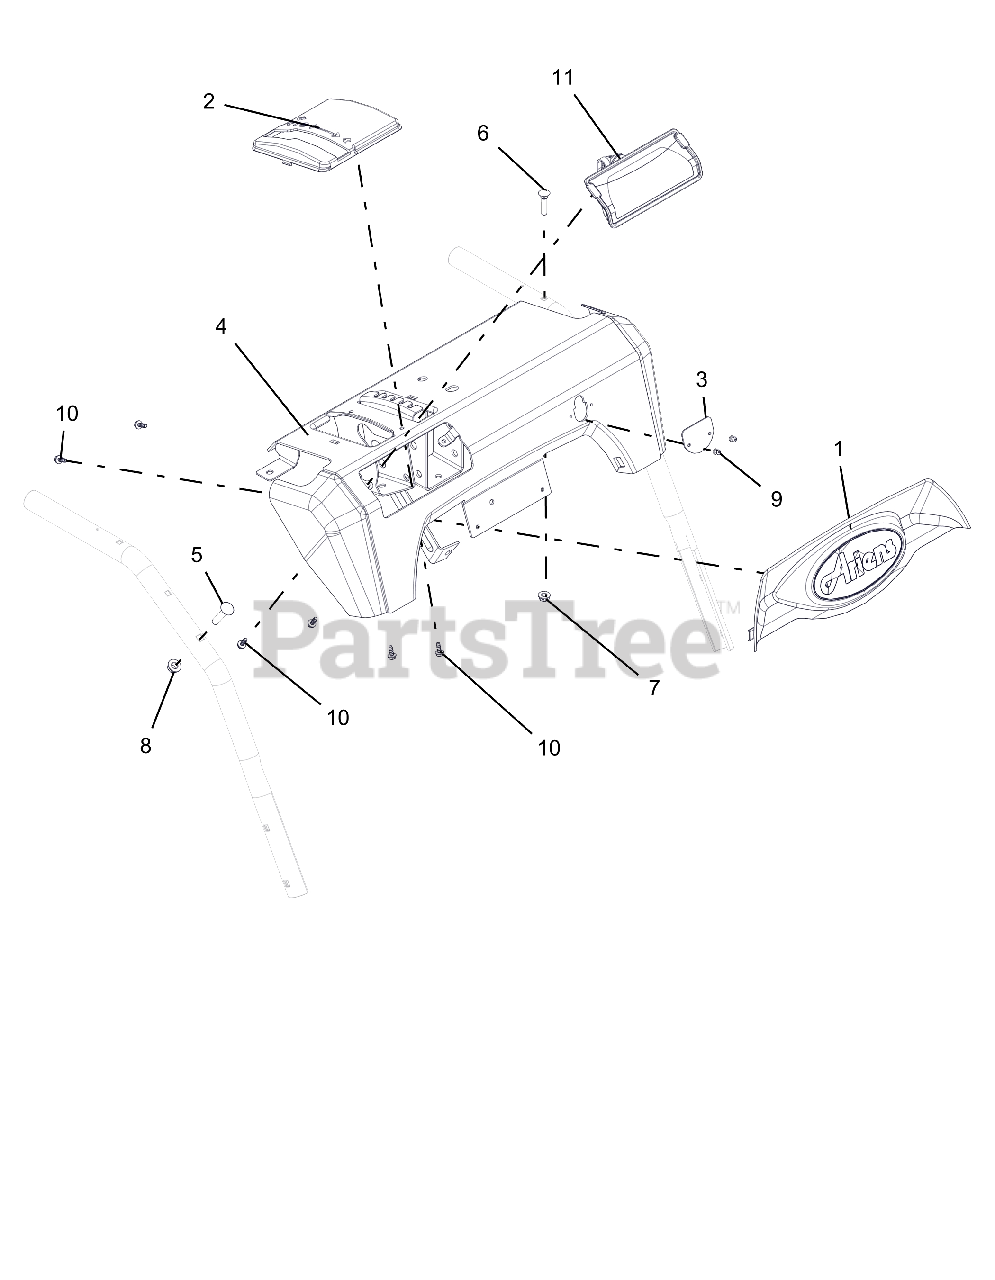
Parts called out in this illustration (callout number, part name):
1	DASH BEZEL, ARIENS LOGO - PRO
2	BEZEL, HYDRO SHIFT BRUSH
3	COVER, DASH BRKT, BRUSH
4	CONTROL PANEL W/DECAL-ARIENS
5	@BLT-RDHDSQNK .31-18X1.50 G5YZ
6	BLT-RDHDXLSQNK.25-20X1.25 G5ZC
7	@NUT-LK-CTR-FLG .25-20 YWZC
8	@NUT-LK-TOP-FLG .31-18 YWZC
9	RVT-POP #43 .125X.313 STL ZINC
10	SCR-TAP #10X.50 BOSS INDHXHD
11	HEADLIGHT ASY, HOLO 15W 2 SHOT
